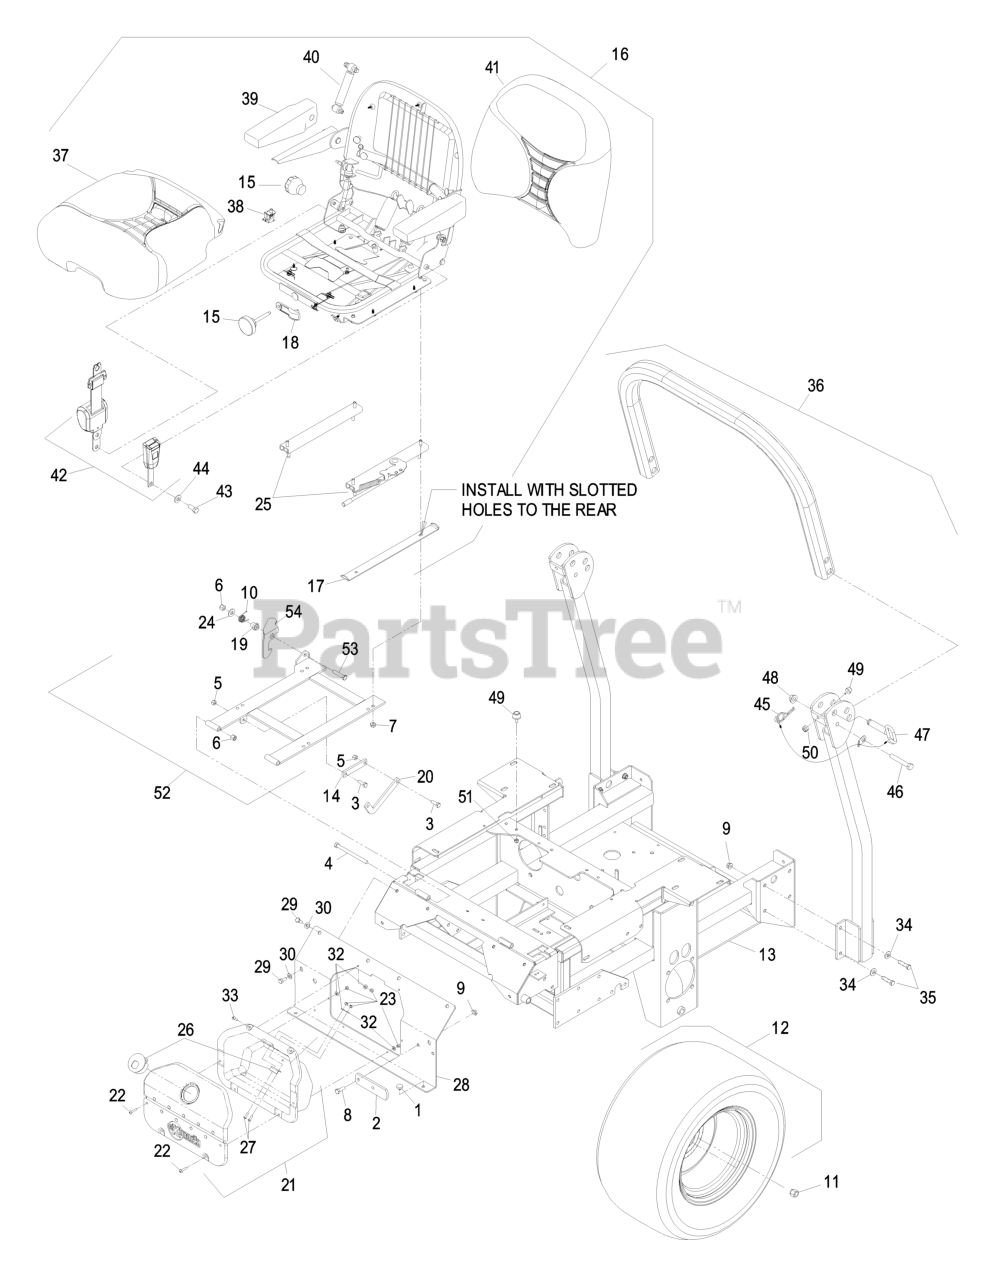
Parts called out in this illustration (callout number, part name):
2	STOP-BRAKE, PARK
3	SCREW-HH
4	SCREW-HH
5	NUT-LOCK, NI
6	NUT-LOCK, NI
8	SCREW-HH
9	NUT-HHF, WHIZ
10	SPRING-TORSION, LATCH
11	NUT-LUG
12	WHEEL AND TIRE ASM
13	ASM,XS ENGINE DECK W/DECA
14	LINK-STOP, SEAT
15	KNOB KIT
16	Lsseat Seat, Suspension
17	STOP-SEAT
18	WEIGHT INDICATOR KIT
19	BUSHING-LATCH, SEAT
21	ASM,CUBBY
23	NUT-LOCK, NI
24	WASHER-FLAT
25	SEAT TRACK KIT
26	LATCH,CUBBY
27	SCREW-PPH
28	ASM, CONSOLE W/DECALS
29	SCREW-HH
30	WASHER-PLAIN
32	WASHER-FLAT
33	SCREW-HEAD, TRUSS
34	WASHER-BELLEVILLE
35	SCREW-HH
36	KIT, 06 XS ROPS
37	BOTTOM CUSHION KIT
39	PAD-ARMREST
40	SHOCK ABSORBER KIT
41	BACK CUSHION KIT
42	RETRACTABLE SEATBELT KIT
43	SCREW-HH
44	WASHER-SPRING
45	HAIRPIN
46	SCREW-HH
47	PIN-FOLD, ROPS
49	BUMPER-RUBBER
50	NUT-LOCK, NI
51	NUT-LOCK, NI
52	SEAT FRAME SINGLE LATCH A
53	SCREW-HH
54	CATCH-LATCH, SINGLE
